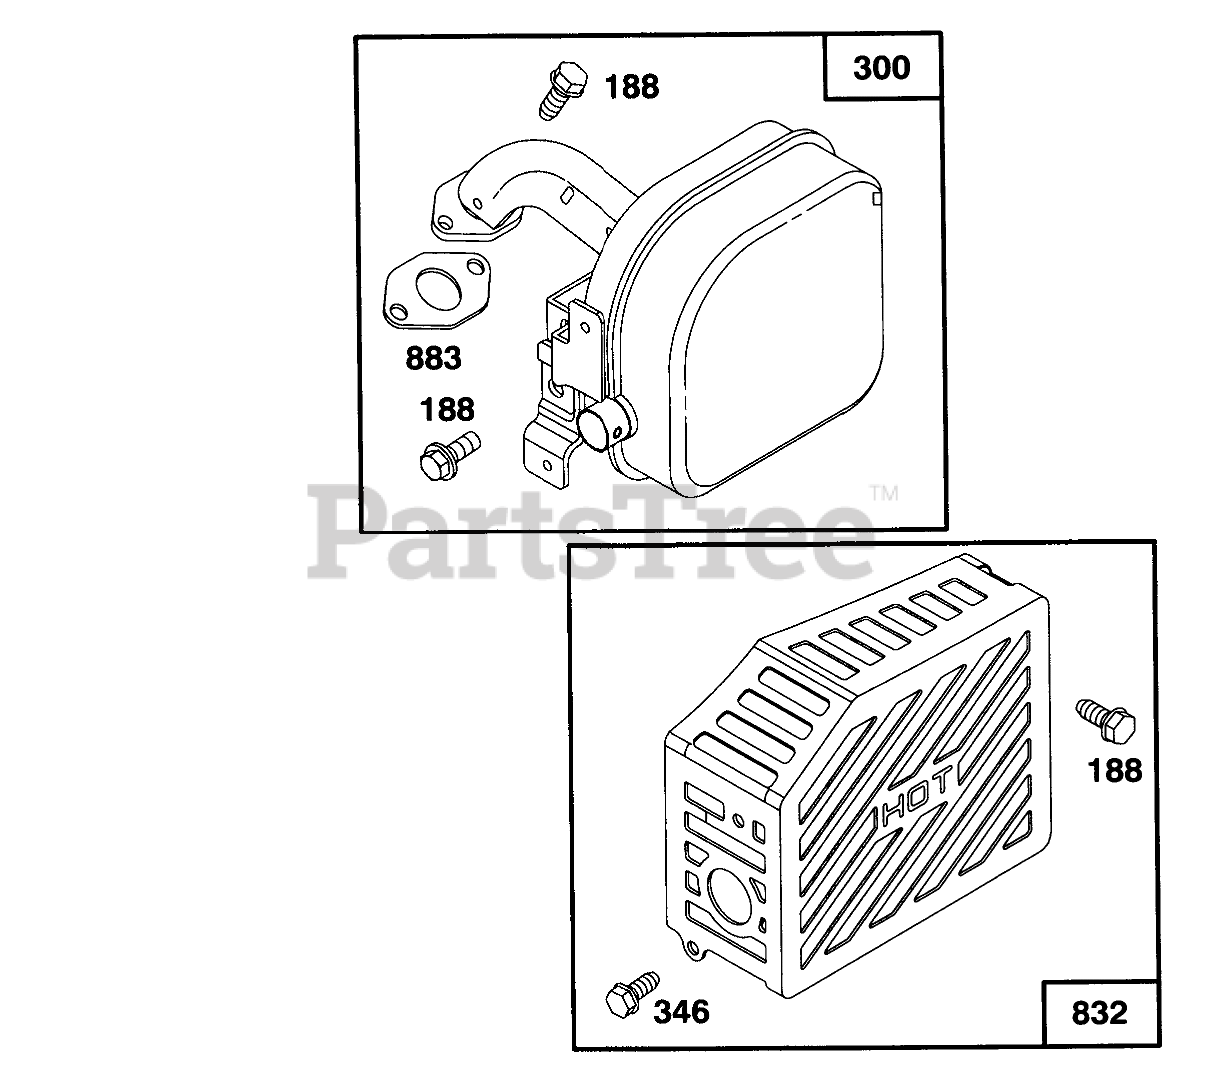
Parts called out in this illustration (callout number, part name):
188	Screw-Cap
300	MUFFLER - EXHAUST
346	Screw-Hex
832	Guard-Muffler
883	EXHAUST GASKET
